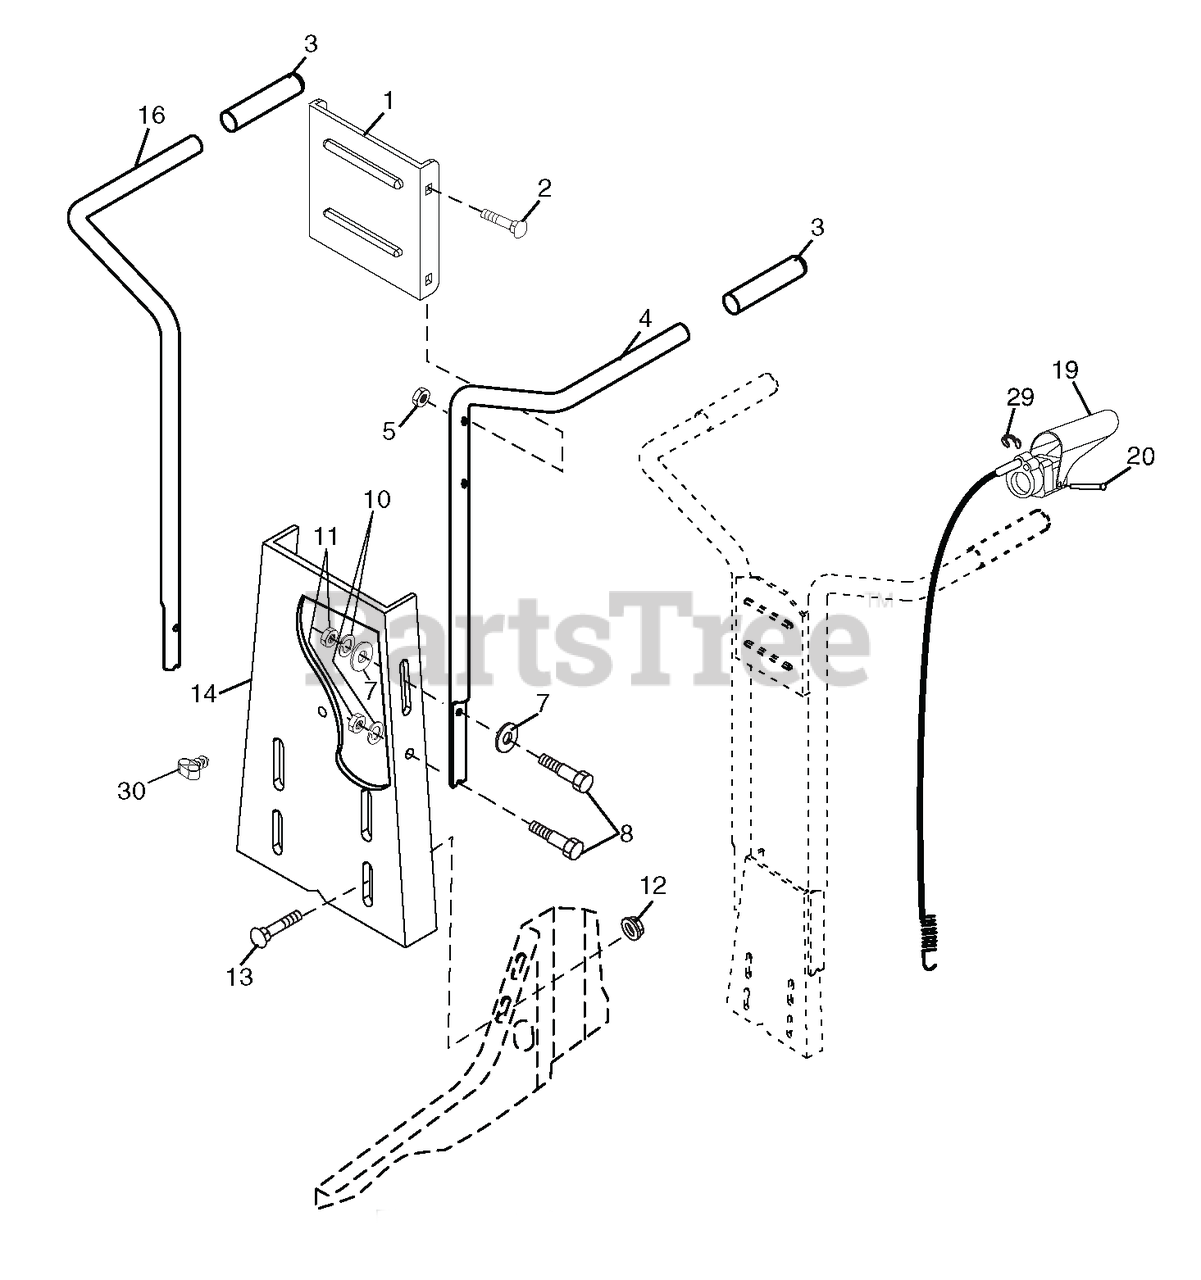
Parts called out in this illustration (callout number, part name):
1	Bracket, Handle
2	Bolt, Carriage 5/16-18 x 1-1/2
3	Grip, Handle
4	Handle, L.H.
5	Nut, Hex
7	Washer 3/8 x 7/8 x 14 Ga.
8	Bolt, Hex Head 5/16-18 x 1-1/4
10	Washer, Lock 5/16
11	Nut, Hex 5/16-18
12	Nut, Hex, Flanged 5/16-18
13	Bolt, Carriage, Gr. 5 5/16-18
14	Panel, Handle
16	HANDLE, R.H.
19	Tine Control Lever Assembly (I
20	Pin, Pivot
29	Retaining Ring
